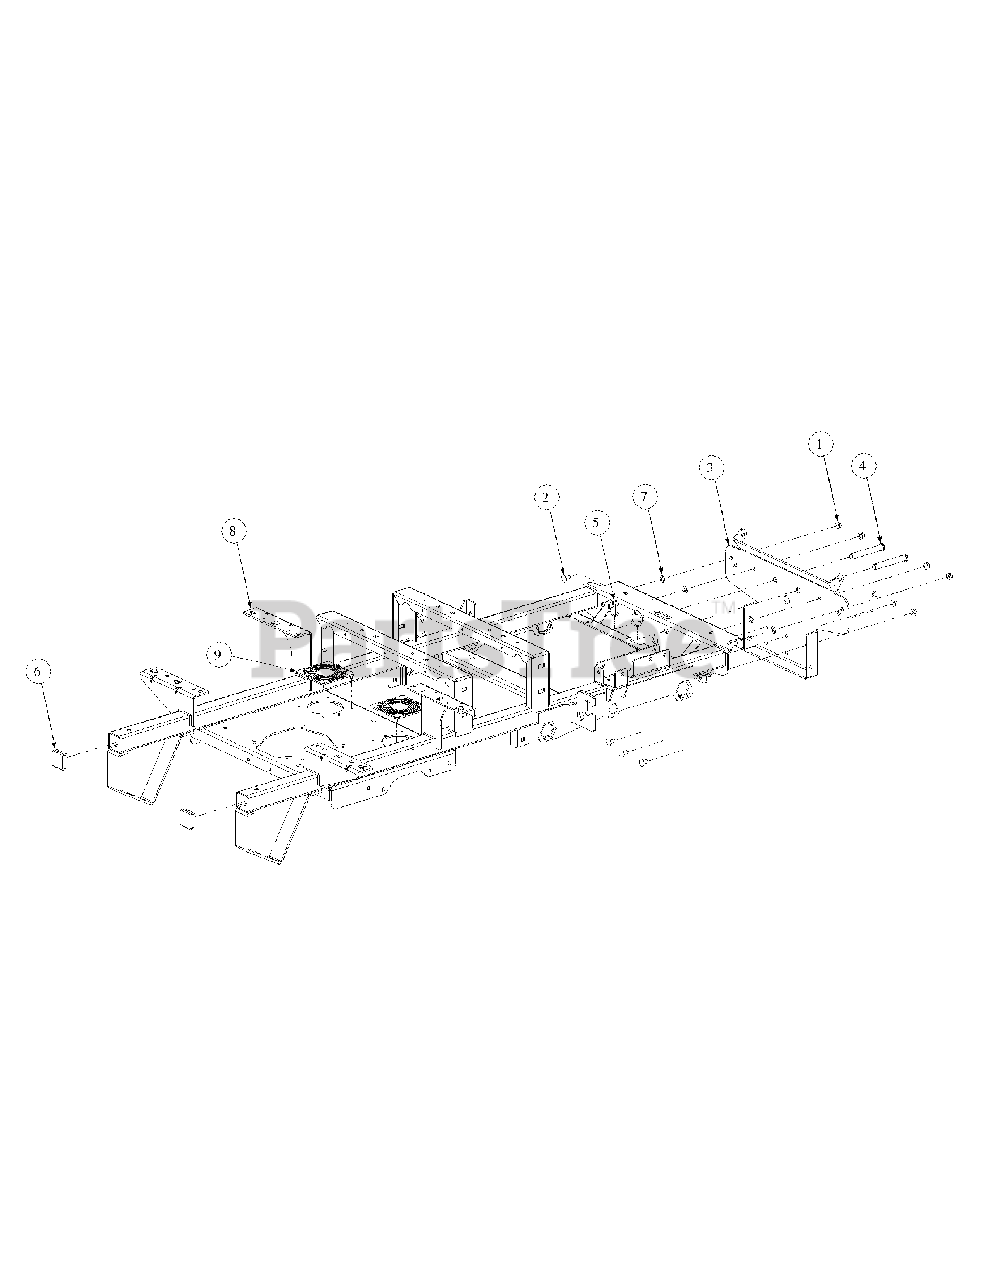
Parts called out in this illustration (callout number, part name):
1	Hex Nut, 3/8-16 Flange Lock
2	Carriage Bolt, 3/8-16 x .75 Long
3	Bracket Assembly, Frame, Front
4	Clevis Pin, .625 Dia x 4.375 Long
5	Linch Pin, 3/16 Dia.
6	Plug, Square Tube
7	Push Retainer, 3/8
8	Frame Assembly
9	Cover, Hydro Fan
